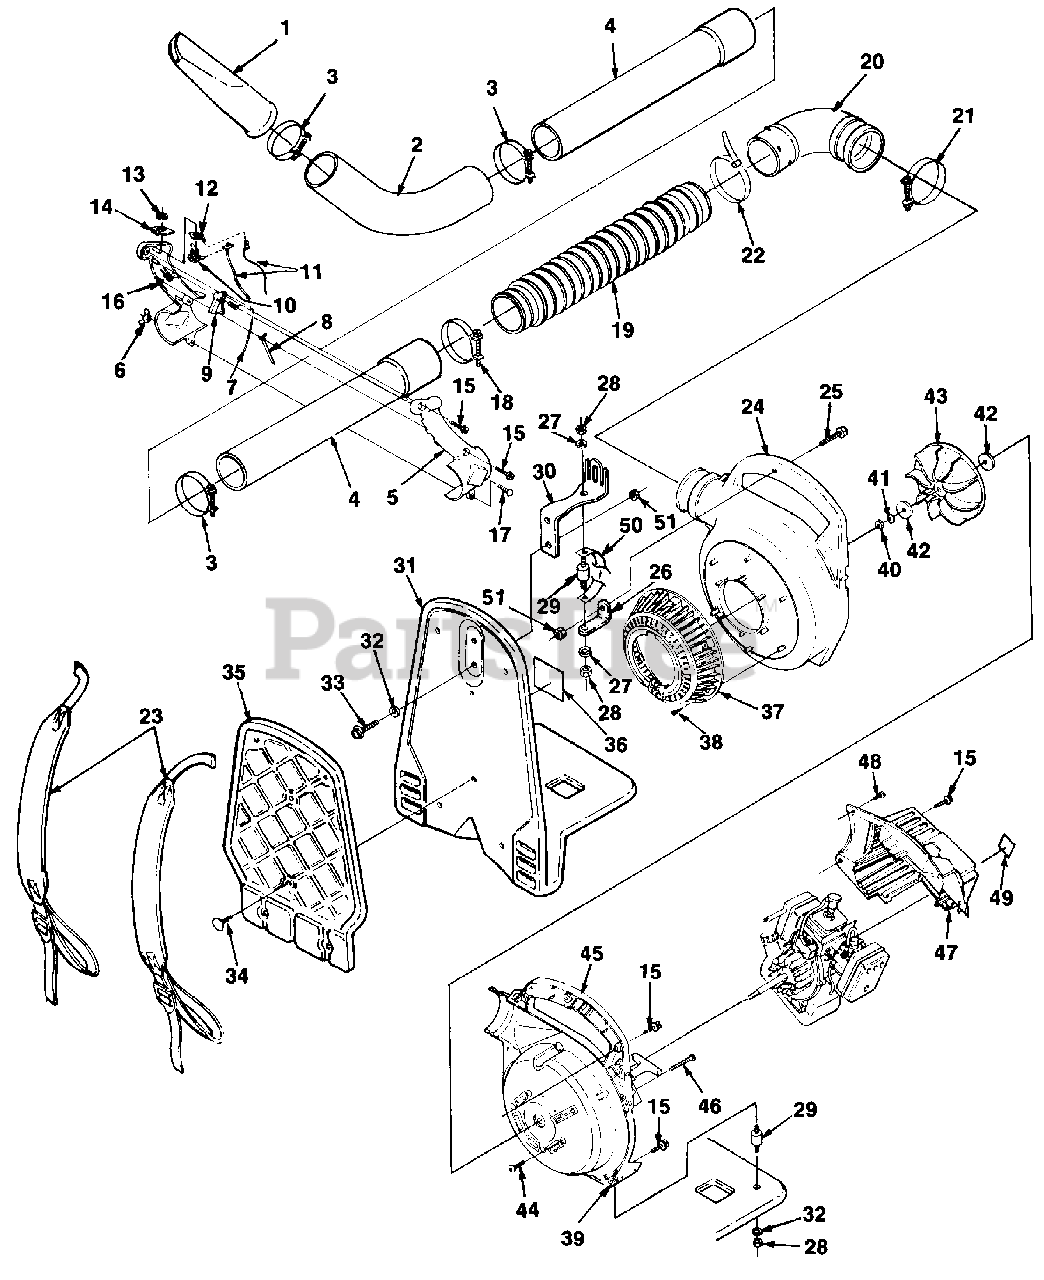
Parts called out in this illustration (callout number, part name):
1	NOZZLE- Sweeper
2	TUBE- Curved
4	TUBING- Straight
5	HANDLE- Control (right)
6	NUT- Wing (10-24)
7	CABLE- Throttle
8	LATCH- Trigger
9	TRIGGER
10	SWITCH- Toggle
11	LEAD & TERMINAL
12	WASHER- Grounding
13	NUT- Toggle Switch
14	PLATE- Indicating
15	SCREW- Thd. forming plastite (#10 x 3/4")
16	HANDLE- Control (left)
17	BOLT- Rib neck (10-24 x 7/8")
19	BELLOWS- Plastic
20	ELBOW- Curved
22	TIE- Cable
23	HARNESS- Shoulder
24	HOUSING- Volute (outer)
25	SCREW- (1/4-20 x 1 1/4")
26	BRACKET- Isolator
27	WASHER- Lock
28	NUT- Hex (1/4-20)
29	ISOLATOR
30	BRACKET- Frame
31	FRAME
32	WASHER- Flat (1/4")
33	SCREW- (1/4-20 x 3/4")
34	CLIP- Push
35	PAD- Foam
36	DECAL- Warning
38	SCREW- Plastite (#6 x 3/8")
39	NUT- Square (1/4-20)
40	NUT- Hex (5/16-24)
41	WASHER- Belleville (5/16")
42	WASHER- Fan
43	FAN- Blower
44	SCREW- Taptite (10-24 x 3/4")
45	HOUSING- Volute (inner) w/decal
46	SCREW-Hex hd. plastite (10 x 1 5/8")
47	SHROUD
48	SCREW- Thd. forming (#8 x 1/2")
49	DECAL- Choke/Run
50	SAFETY STRAP
51	NUT- Locking hex
